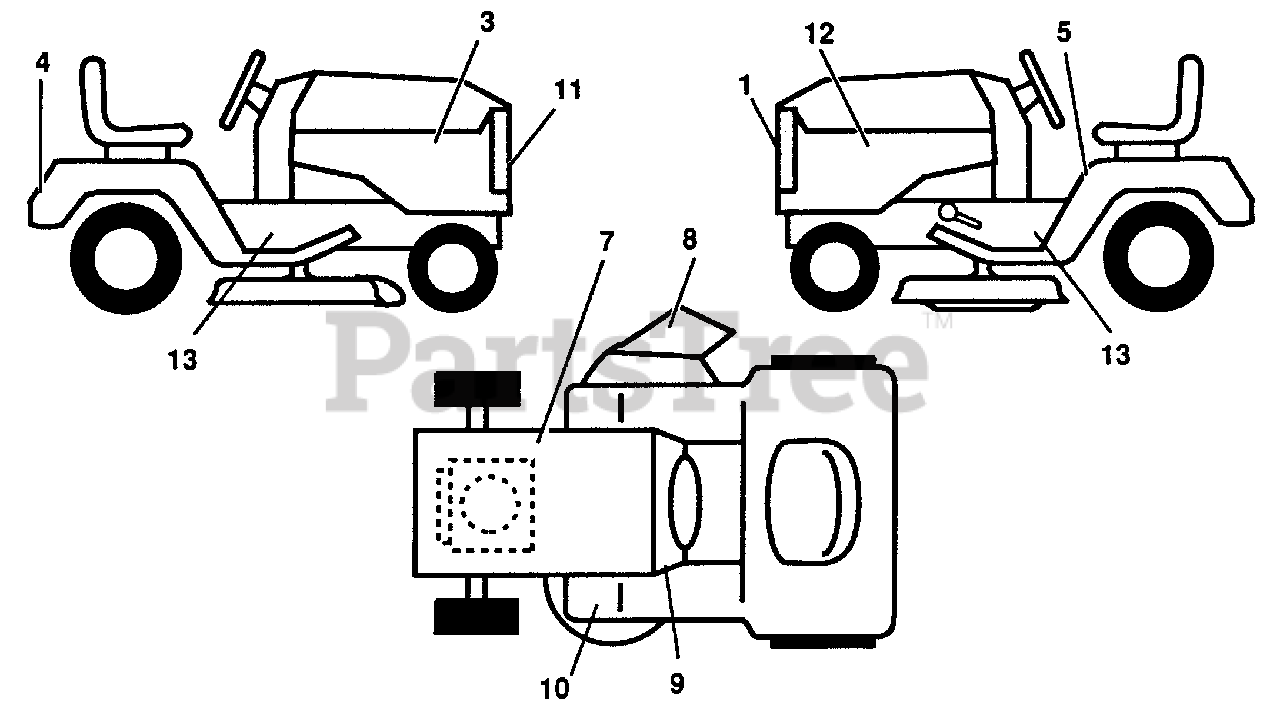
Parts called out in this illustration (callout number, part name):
1	Decal, Logo, Grill
3	Decal, Hood, RH
4	Decal, Logo, Fender
5	Decal, Caution, English/French)
7	Decal, Caution, Battery
8	Decal, Warning (Multi-Long)
9	Decal, Operating Instructions, (English/French)
10	Decal, Clutch/Brake (English/French)
11	Decal, Belt Adjustment PTO (English/French)
12	Decal, Hood LH
13	Decal, Chassis
